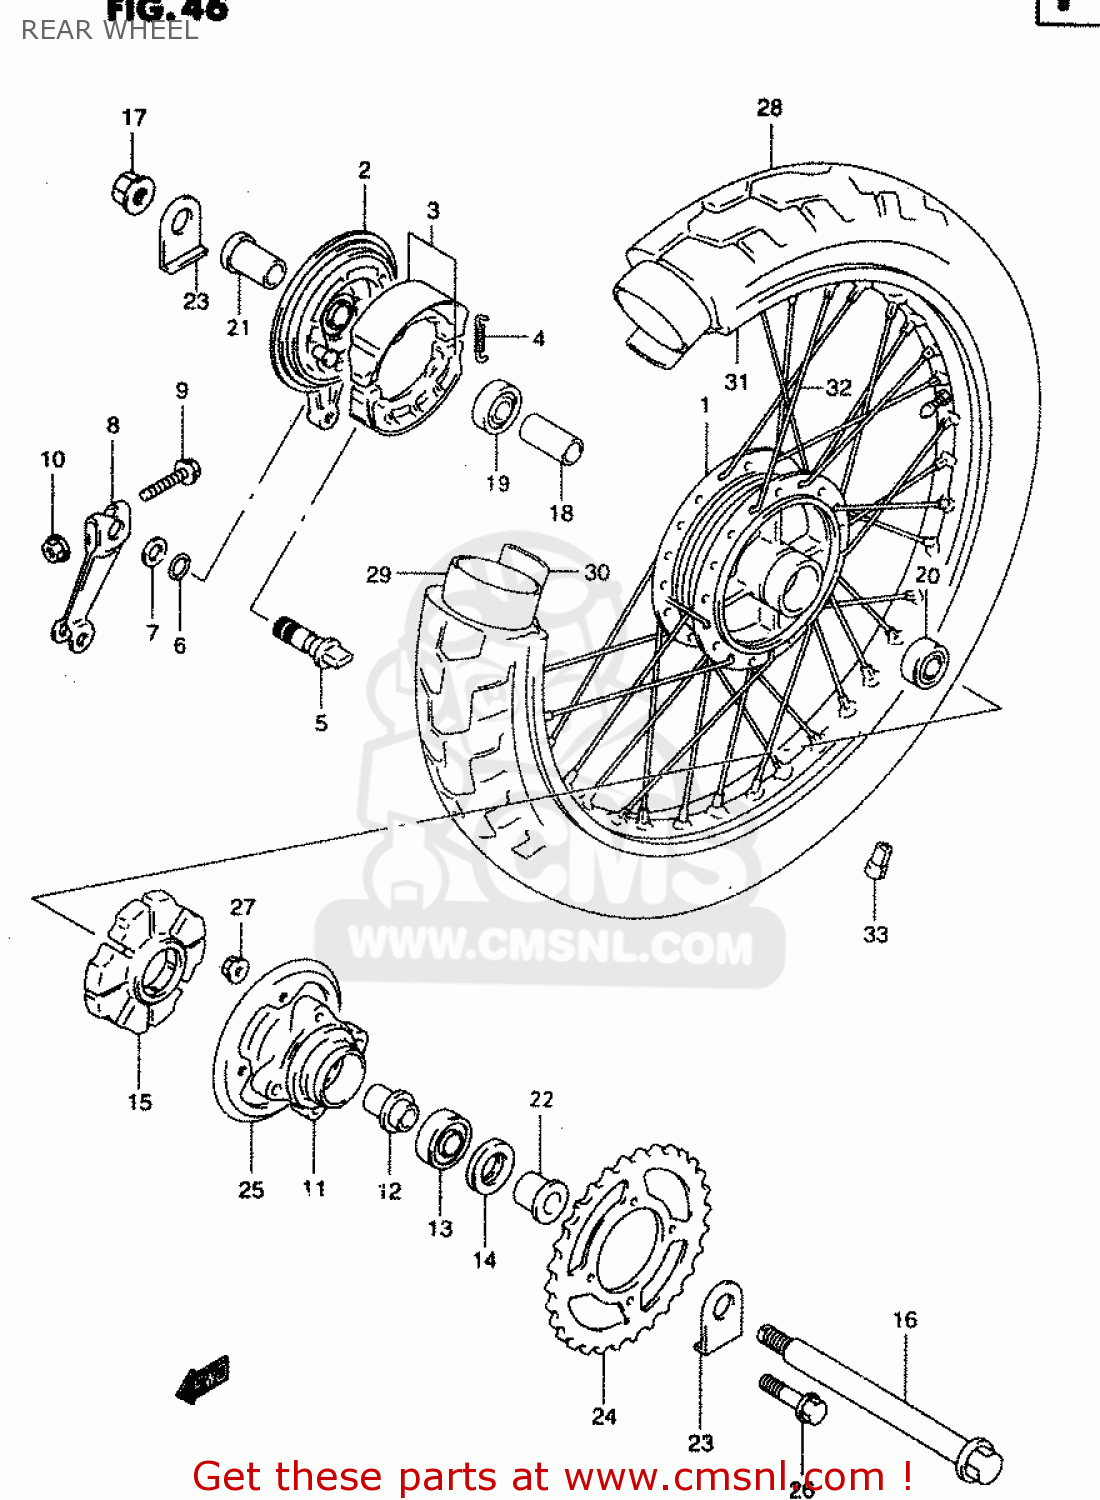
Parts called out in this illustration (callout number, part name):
1	HUB,RR WHEEL
2	PANEL,RR BRAKE ANCHOR
3	SHOE SET,BRAKE (NAS)
4	SPRING(L:34)
5	CAM,BRAKE
6	O RING(D:2.5,ID:13.8)
7	WASHER(14.5X22X1.6)
8	LEVER,RR BRAKE CAM
9	BOLT
10	NUT
11	DRUM,RR SPROCKET MOUNTING
12	RETAINER,RR SPROCKET DRUM
13	BEARING(20X47X14)
14	SEAL,OIL(28X47X7)
15	ABSORBER ASSY,HUB SHOCK
16	AXLE,RR
17	NUT
18	SPACER(15.3X21.7X63)
19	BEARING
20	BEARING
21	SPACER,RR AXLE,R
22	SPACER,RR AXLE,L
23	WASHER,CHAIN ADJUSTER GUIDE
24	SPROCKET,RR(NT:41-520)
25	GUIDE,RR SPROCKET CHAIN
26	BOLT(10X40)
27	NUT
28	TIRE,RR(130/90-15)
29	TUBE ASSY,WHEEL INNER
30	PROTECTOR,WHL INR TUBE
31	RIM,RR WHEEL(15XMT3.00)
32	SPOKE SET,RR WHEEL
33	BALANCER,WHEEL (B)
